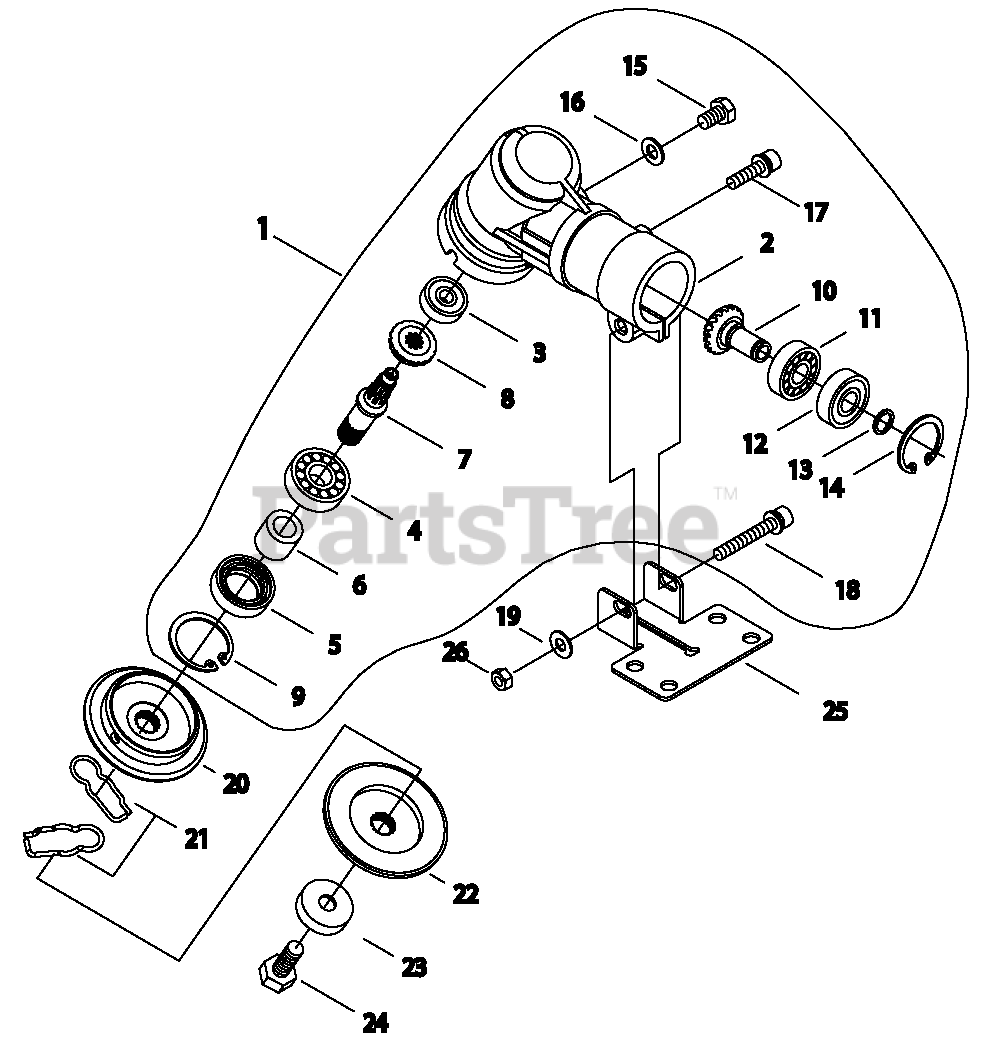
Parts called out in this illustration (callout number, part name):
1	GEAR CASE ASSY
2	CASE, GEAR
3	BEARING, BALL - 6000
4	BEARING, BALL - 6202
5	SEAL, OIL
6	COLLAR
7	GEAR - SHAFT
8	GEAR - BEVEL
9	RING, RETAINING - 35
10	GEAR - SHAFT
11	BEARING, BALL - 6001
12	BEARING, BALL - 6001ZZ
13	RING, RETAINING
14	RING, RETAINING - 28
15	BOLT - 6X10
16	WASHER
17	BOLT - 6X14
18	SCREW - 6X40
19	WASHER - 6
20	ADAPTOR, BLADE - UPPER
21	CLIP
22	ADAPTOR, BLADE - LOWER
23	GUARD
24	BOLT - 10 -- LEFT HAND
25	CLAMP - LOWER
26	LOCKNUT - 6
